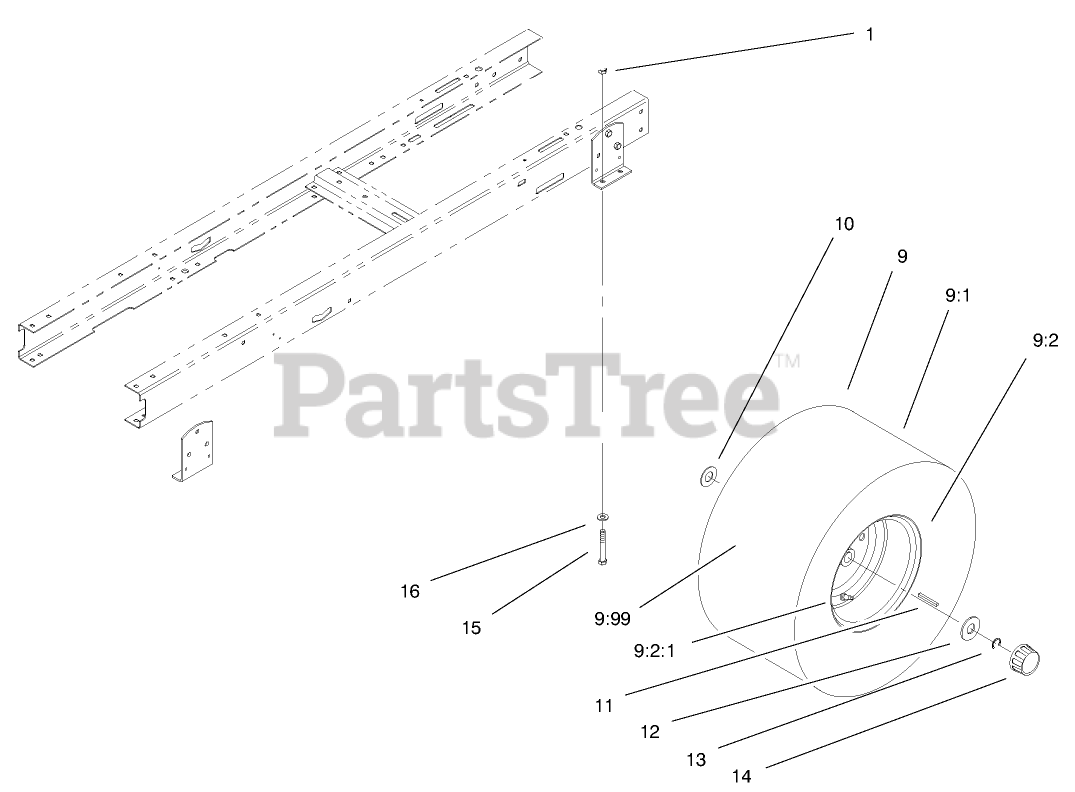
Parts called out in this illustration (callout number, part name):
1	NUT-LOCK, NI
9	Wheel tire ASM,Rear
9:1	TIRE
10	WASHER-THRUST
11	KEY-SQUARE
12	WASHER-PLAIN
13	E-RING
14	CAP-HUB
15	SCREW-HH
16	WASHER-PLAIN
